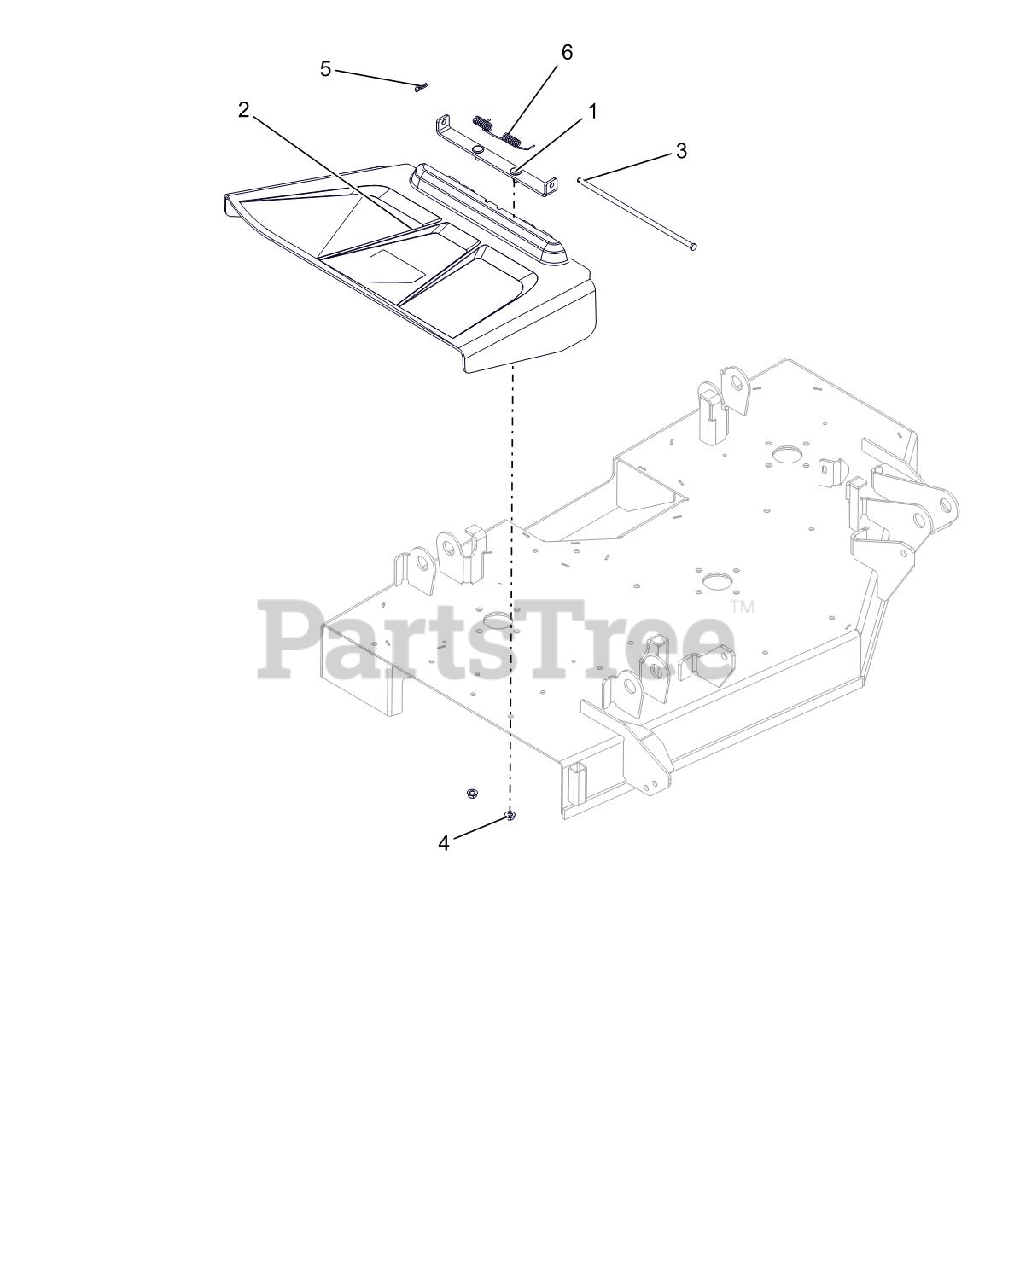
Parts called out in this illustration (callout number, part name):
1	WLDMT, CHUTE MT BRKT
2	CHUTE, SIDE DISCHARGE
3	PIN, 5/16 X 10.5
4	NUT-LK-TOP-FLG .31-18 YWZC
5	PIN-HAIR INT .08X.18X1.18 YWZC
6	SPRING-TORSION
